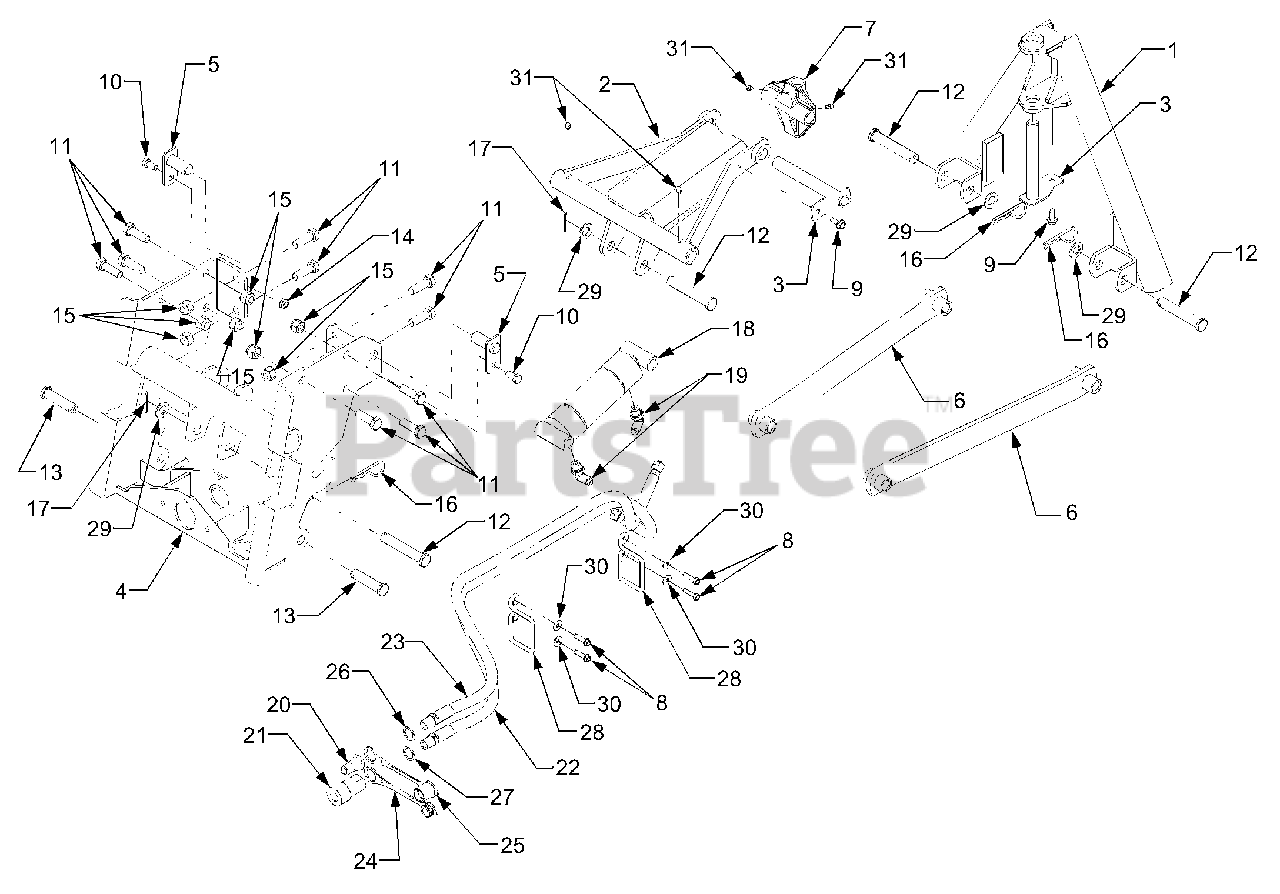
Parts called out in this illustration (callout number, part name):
1	Frame, Hitch A
2	Link, Top Pivot
3	Pin Assembly, Hitch Pivot
4	Brace Assembly, Front Hitch
5	Pin Assembly, Hitch Pivot
6	Arm, Front Hitch
7	Housing, Pivot
8	Screw, Hex Wash Hd Tapp 1/4-20 x 1.0
9	Screw, Hex Wash Hd Tapp 5/16-18 x .75
10	Screw, Hex Cap Lock 3/8-16 x .75 GR5
11	Screw, Hex Cap 1/2-13 x 1.50 GR5
12	Pin, Clevis, .625 x 3.45
13	Pin, Clevis, .625 x 2.313
14	Nut, Hex Insert Lock, 3/8-16 GR5
15	Nut, Hex Insert Lock, 1/2-13 GR8
16	Pin, Internal Cotter
17	Pin, Cotter, 1/8 x 1.25
18	Cylinder, Hitch Lift
19	Fitting, 90°.
20	Coupling, Hydraulic - Male
21	Coupling, Hydraulic - Female
22	Hose, Hydraulic, 1/4 ID x 42.0
23	Hose, Hydraulic, 1/4 ID x 46.0
24	Plug, Hydraulic Coupler - Male
25	Plug, Hydraulic Coupler - Female
26	Washer, Indicator - Green
27	Washer, Indicator - Blue
28	Rod, Hose Support
29	Washer, Flat, .65 x 1,25 x .075
30	Washer, Flat, .26 x .72 x .06
31	Fitting, Lube
